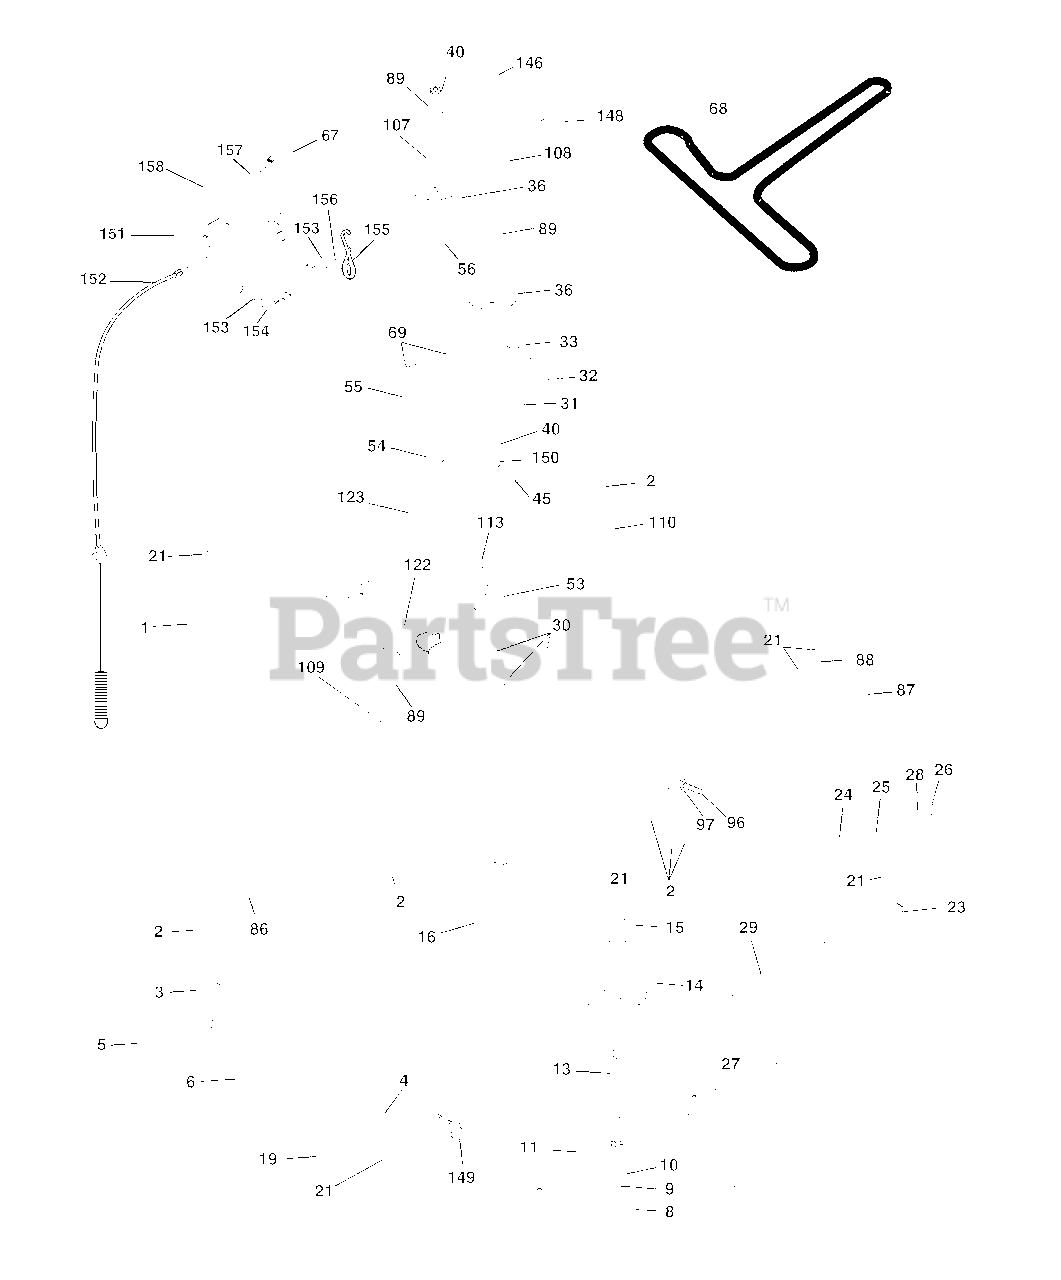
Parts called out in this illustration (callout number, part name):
1	Mower Housing Assembly
2	Bolt Carriage 5/16-18 x 3/4
3	Bracket Asm Fr. Sway Bar
4	Bracket Deck Sway Bar 38"/42"
5	Retainer Spring
6	Sway Bar Deck
8	Bolt 3/8-24 x 1.25 Grade 8
9	Washer, Lock 3/8
10	Washer, Hardened
11	Blade Mower
13	Shaft Assembly, Mandrel, Vented
14	Housing, Mandrel, Vented
15	Bearing, Ball, Mandrel
16	Stripper, Mower Deck
19	Bolt, Shoulder
21	Nut
23	Bracket, Mower Deflector
24	Cap, Sleeve
25	Spring, Torsion, Deflector
27	Shield, Deflector
28	Washer 11/32 x 5/8 x 16 Gauge
29	Rod, Hinge
30	Screw Thdrol. Hex
31	Washer, Spacer
32	Pulley, Mandrel
33	Nut, Toplock
36	Pulley, Idler, Flat
40	Nut, Crownlock 3/8-16 Unc
45	Retainer
53	Brake Assembly
54	Washer, Hardened
55	Idler Arm Assembly
56	Spacer, Retainer
68	V-Belt, 42" Mower
69	Pin, Cotter 3/32 x 3/4
86	Runner, LH
87	Runner, RH
88	Washer 11/32 x 3/4 x 16 Ga
89	Washer 13/32 x 1 x 12 Ga.
107	Spacer Retainer
108	Stiffener, Idler Arm
109	Bolt, Hex Hd 3/8-16 x 2-1/2
110	Upstop Deck Front 38"
113	Screw 5/16-1/ x 3/4
122	Rod, Brake LH
123	Rod, Brake RH
146	Bolt Carriage Idler
148	Spring Return Idler
149	Retainer Spring Yellow
150	Washer 9/32 x 3/4 x 16 Ga.
151	Bracket Clutch Cable
152	Clutch Cable 38"/46"
153	Washer Flat 3/8" Type B
154	Spring Retainer
155	Spring Retention LVR CLTCH CAB
156	Spacer Clutch Cable
157	Rod Clutch Cable 3/8"
158	Screw Hex Thd Cut 1/4-20 x 5/8
